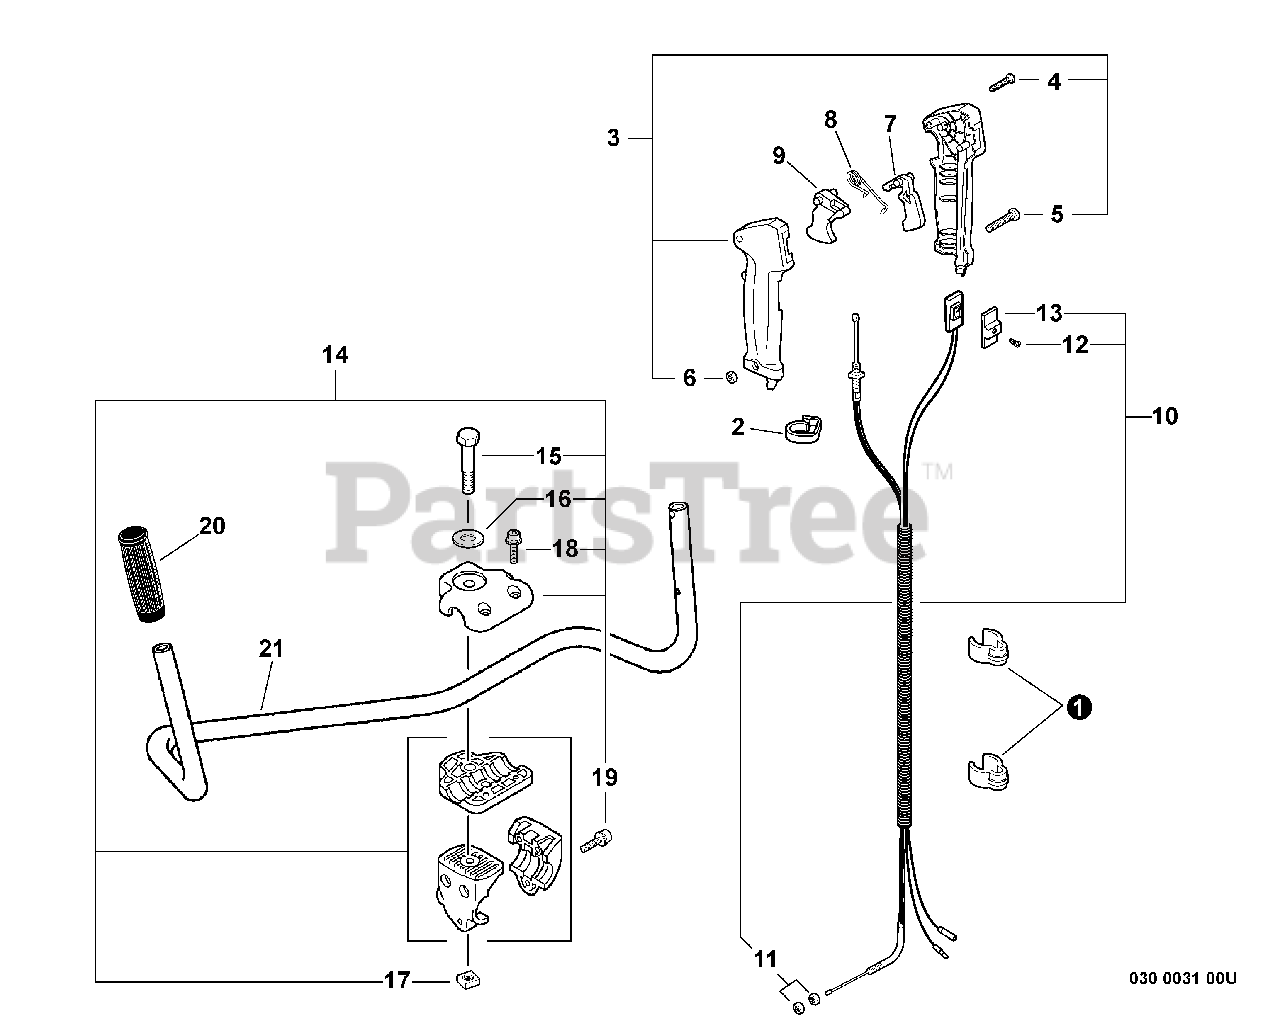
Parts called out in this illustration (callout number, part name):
3	THROTTLE CONTROL ASSY
4	SCREW - 3X25
5	SCREW - 5X30
7	LOCKOUT, THROTTLE
8	SPRING, LOCKOUT LEVER
9	TRIGGER, THROTTLE
10	CONTROL CABLE ASSY
12	SCREW - 3X10
13	KNOB, SWITCH - ORANGE
14	HANDLE BRACKET KIT
15	BOLT - 8X55
16	WASHER - 8
18	SCREW - 5X20
19	SCREW - 5X30
20	GRIP, HANDLE - LEFT
21	HANDLE - FRONT
